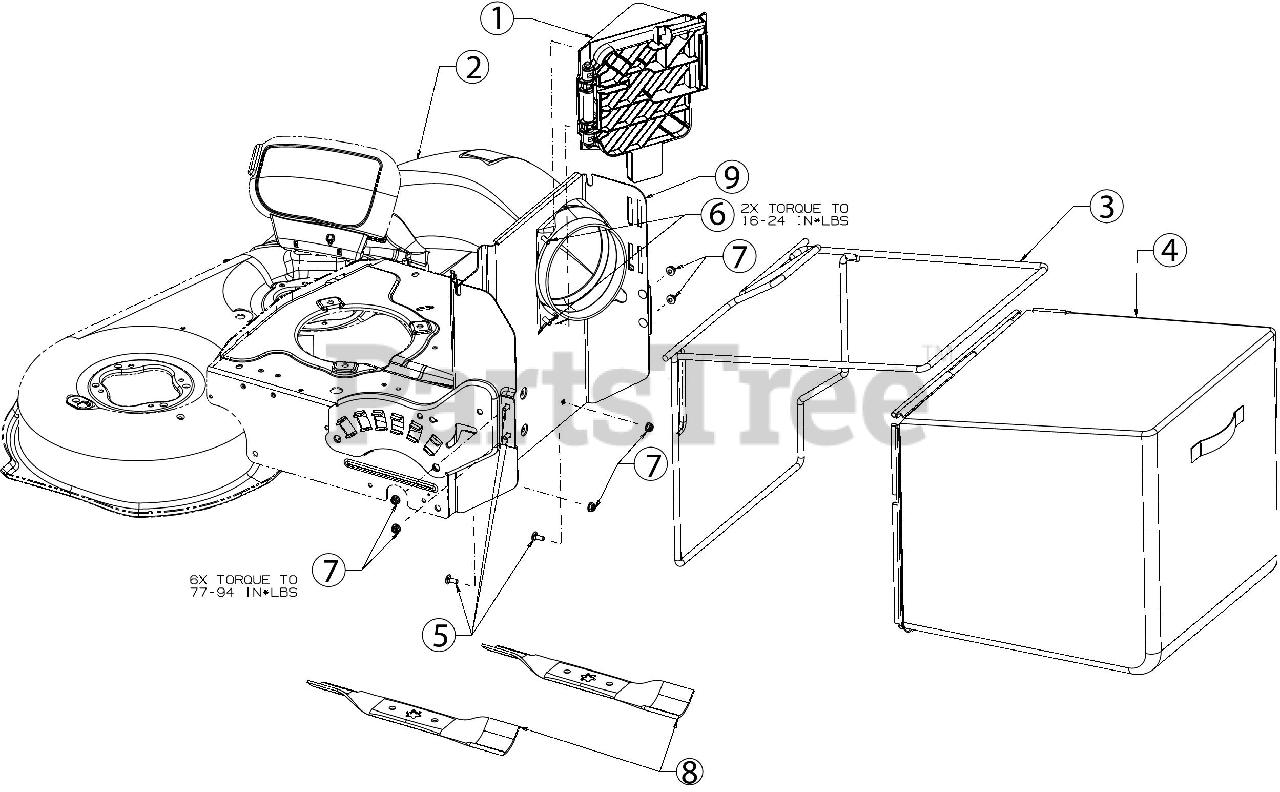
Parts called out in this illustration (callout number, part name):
1	GRASSBAG DOOR ASSEMBLY
2	CHUTE ASSEMBLY
4	GRASSBAG - CUB CADET 28" MOWER
4	GRASSBAG - PLAIN 28" MOWER
5	CARRIAGE BOLT 1/4-20 x .62
6	SCREW 1/4 x .750
7	FLANGE LOCK NUT
8	BLADE (HI LIFT) (14.2)
